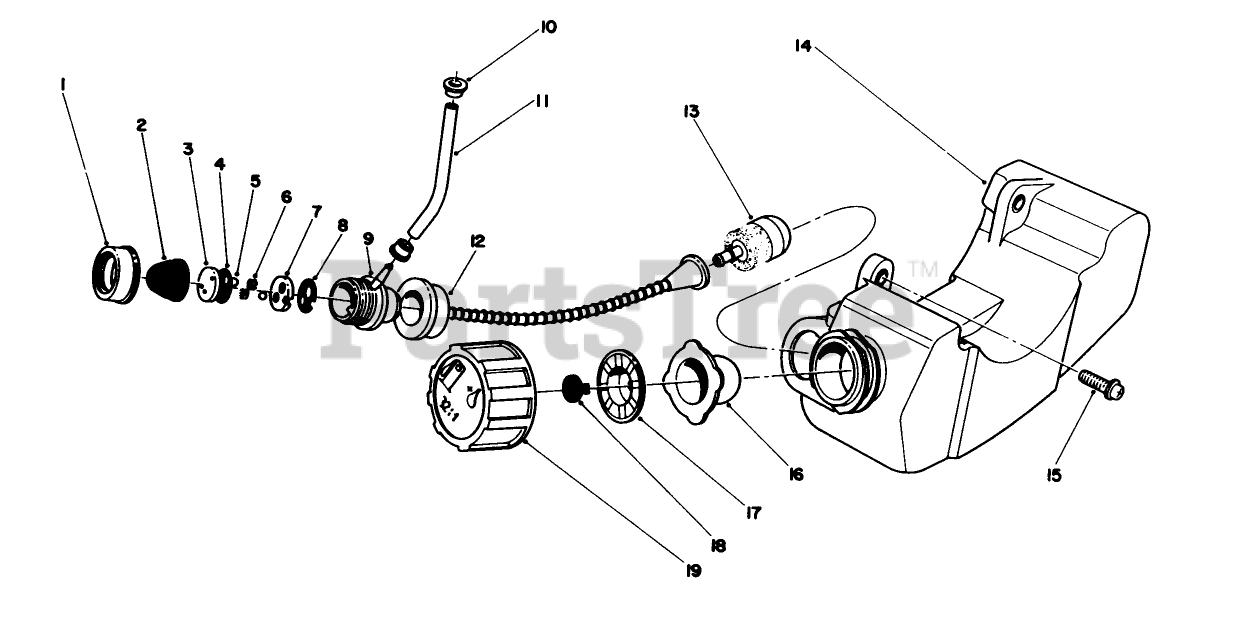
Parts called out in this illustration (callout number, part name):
1	PUMP CAP
3	SEAT VALVE
4	GASKET
6	SPONGE
7	SEAT VALVE
8	GASKET
9	Pump-Primer (Incl. Ref. #1-8)
11	FUEL TUBE
12	SUCTION HOSE
13	FUEL FILTER
14	Fuel Tank Assembly (Incl. Ref. #1-9, 12, 13, 16-19)
15	Screw
16	GASKET - PACKING
17	HOLDER
18	BREATHER VALVE
19	TANK CAP
